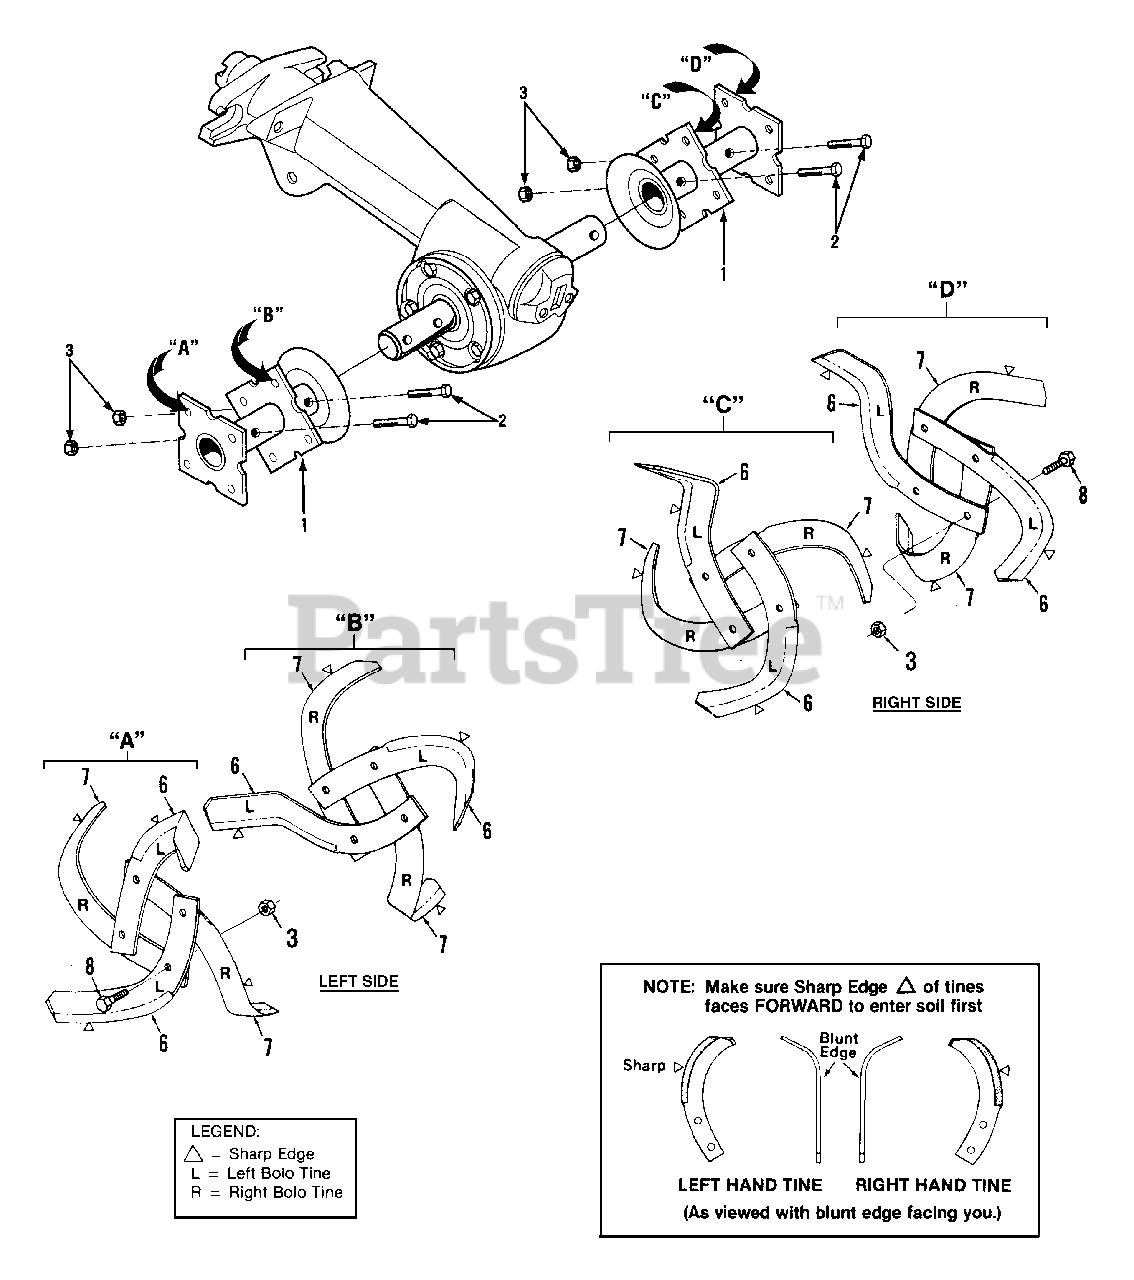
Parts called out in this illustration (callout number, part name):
1	Tine Holder-welded steel, fits left or right sides
2	Bolt-hex hd., 3/8-16 x 2"
3	Locknut-hex, 3/8"-16
6	Bolo Tine-single, left hand. Tine is stamped either "EL" or "AL"
7	Bolo Tine-single, right hand. Tine is stamped either "ER" or "AR"
8	Bolt-hex hd., 3/8-16 x 1"
